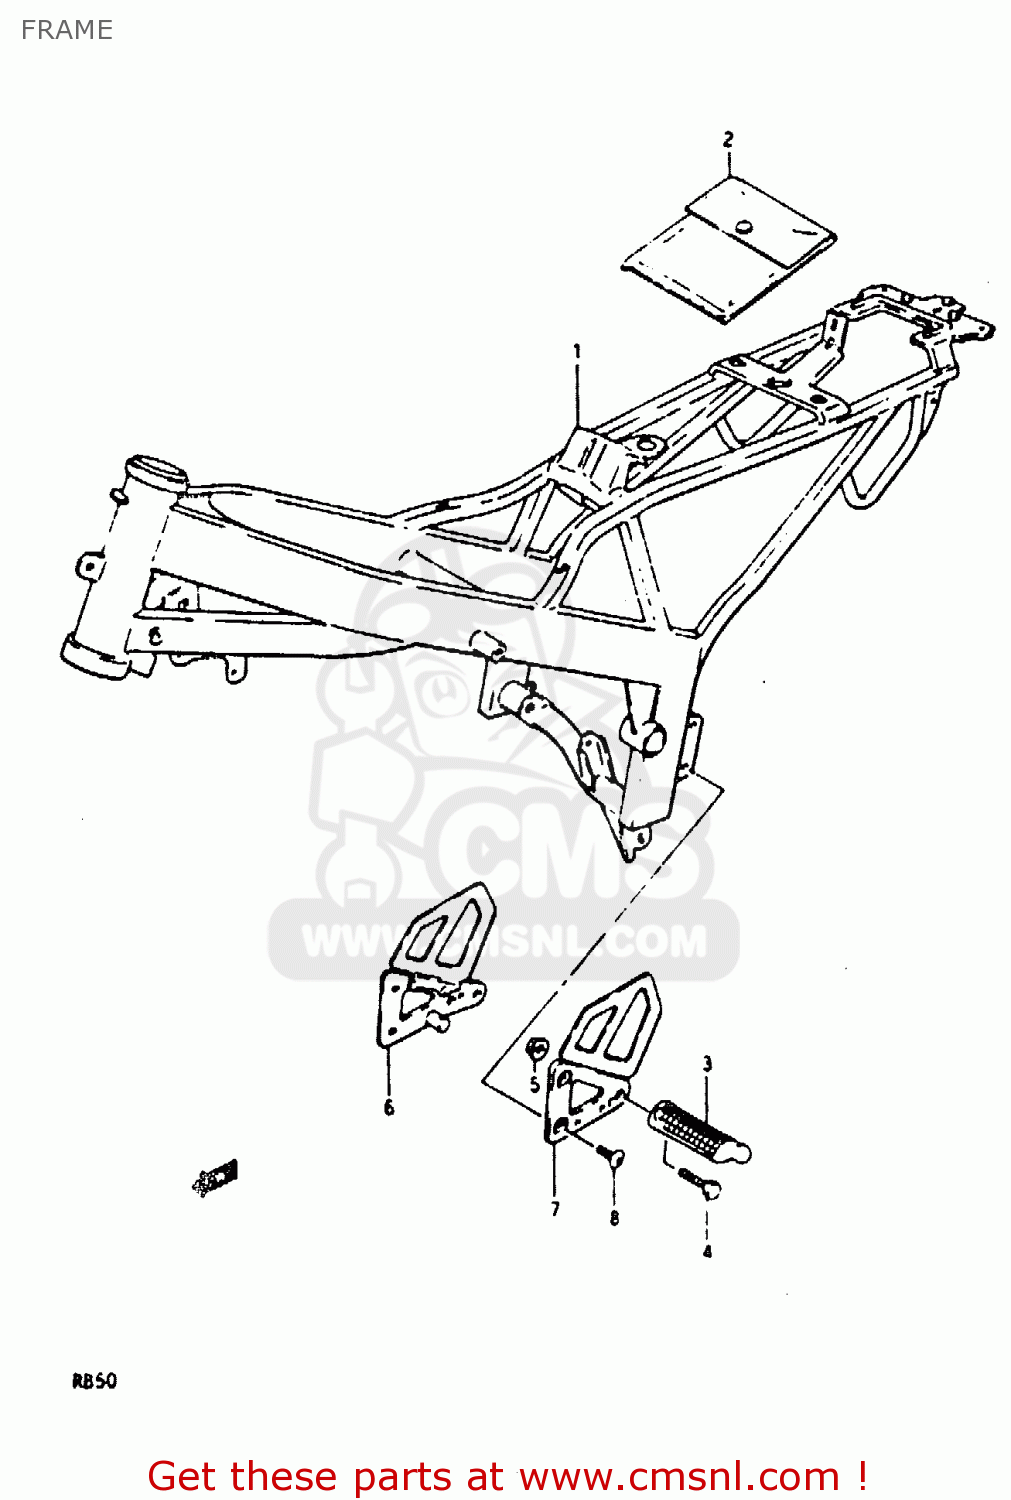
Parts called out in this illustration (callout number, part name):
1	FRAME
2	BAG,OWNERS MANUAL
3	BAR,FR FOOTREST
4	BOLT
5	NUT
6	BRACKET,FR FOOTREST,R
7	BRACKET COMP,FRONT FOOTREST
8	BOLT(6X12)
